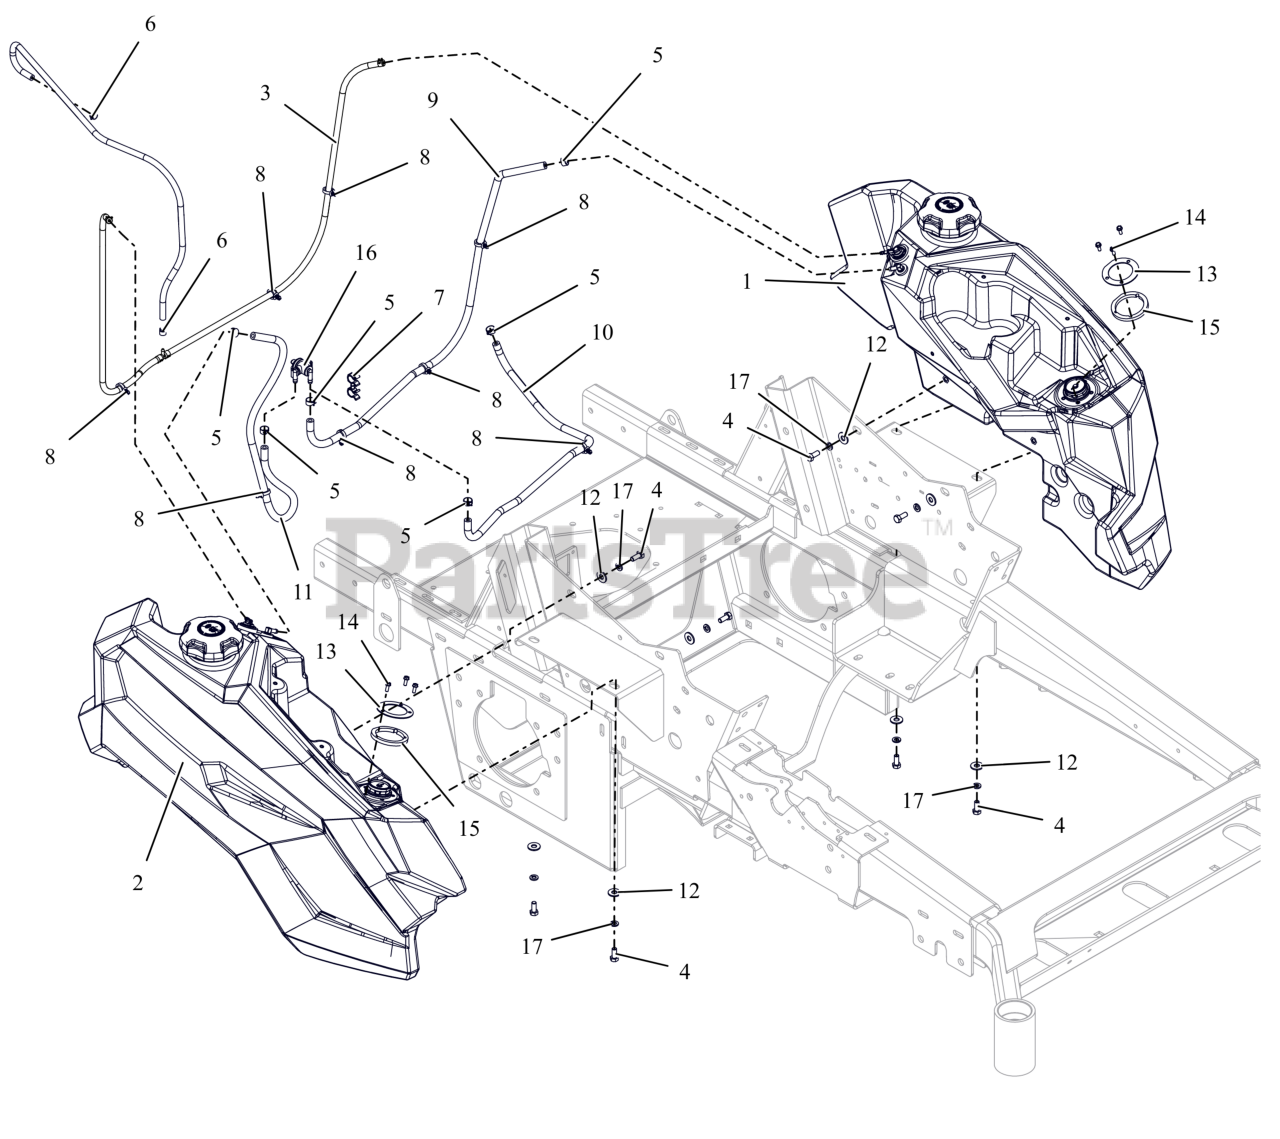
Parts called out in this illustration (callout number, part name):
1	ASM- PT300-500 LH FUEL TANK
1	GAUGE- REMOTE SEALED FUEL
1	GROMMET, REMOTE VENT NITRILE
1	VALVE, COMBINATION VENT 3/16
1	FUEL PICKUP ASSEMBLY
1	CAP, FUEL - 3.50 RATCHET INLET VENT
2	ASM- PT300-500 RH FUEL TANK
2	GAUGE- REMOTE SEALED FUEL
2	GROMMET, REMOTE VENT NITRILE
2	VALVE, COMBINATION VENT 3/16
2	FUEL PICKUP ASSEMBLY
2	CAP, FUEL - 3.50 RATCHET INLET VENT
3	ASM- PT300/500/600 VENT LINE
4	BLT,HEX .31-18X.75 G5 ZCC
5	CLAMP, FUEL LINE
6	CLAMP-HOSE, SPRING .188
7	CLIP-360DEG SWIVEL.500DIA HOSE
8	CLIP- PUSH-IN X-MAS TREE CABLE
9	1 INCH OF HOSE, .25 LOW-PERM BULK GAS
10	1 INCH OF HOSE, .25 LOW-PERM BULK GAS
11	1 INCH OF HOSE, .25 LOW-PERM BULK GAS
12	WSHR,FLT .375X.875X.083 ZCC
13	RETAINER, FUEL GAUGE (BLACK)
14	SCR-MCH 10-24X.50 HWHSTAINLESS
15	SPCR, FUEL GAUGE RETAINER (BLACK)
16	VALVE, FUEL - WITH MAGNET
17	WSHR,LK-REG .312X.078 ZCC
